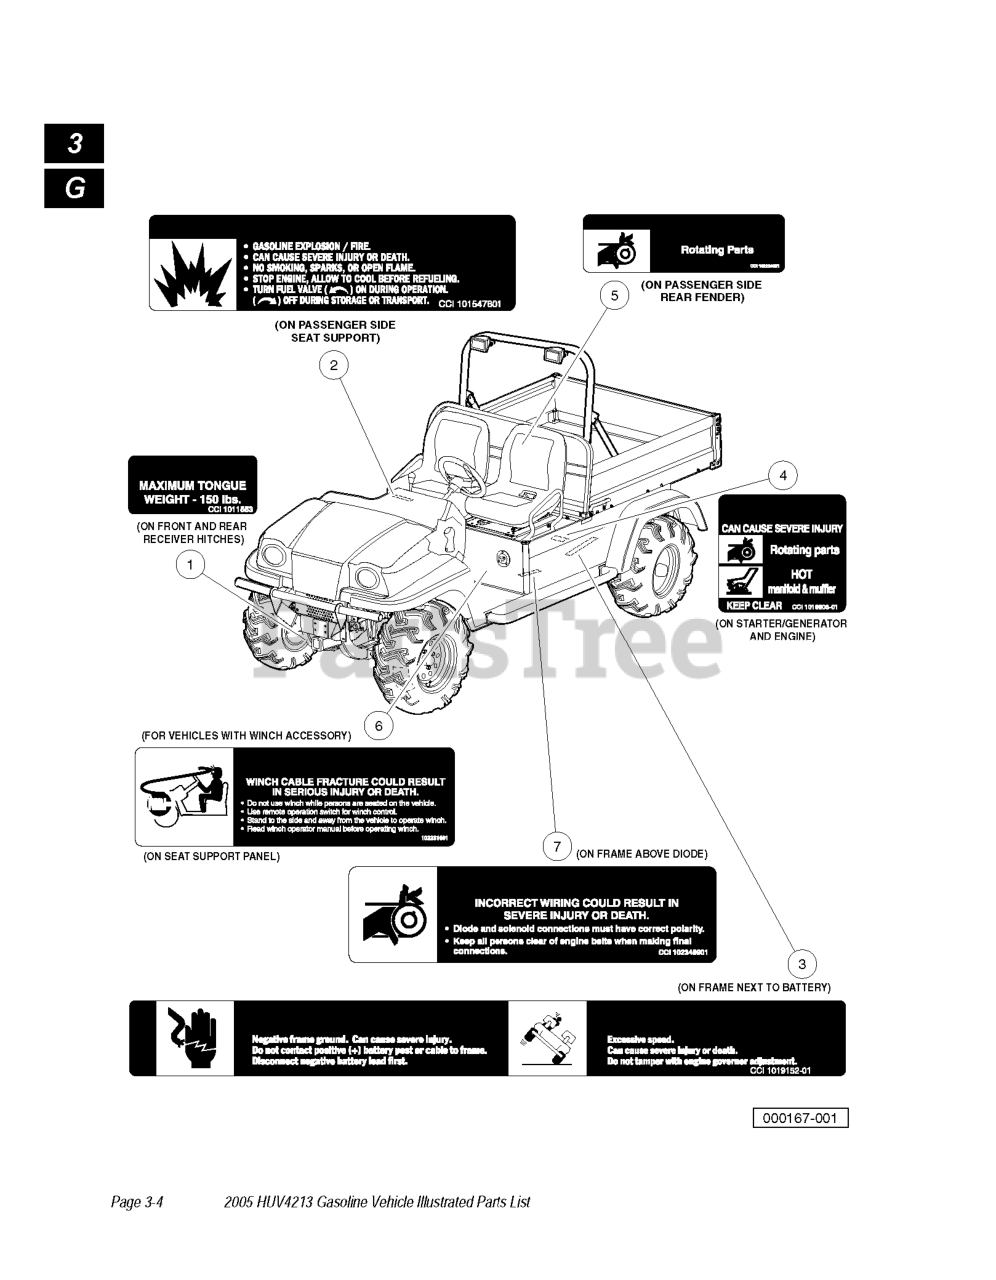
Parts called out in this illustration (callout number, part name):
1	DECAL, TRAILER HITCH
2	DECAL, WARNING - GASOLINE FUEL
3	DECAL, FRAME GROUND, GOV. WARN
4	DECAL, ROTATING PARTS/MANIFOLD
5	DECAL-ROTATING PARTS
6	DECAL-WINCH KIT
7	DECAL, DIODE SAFETY
